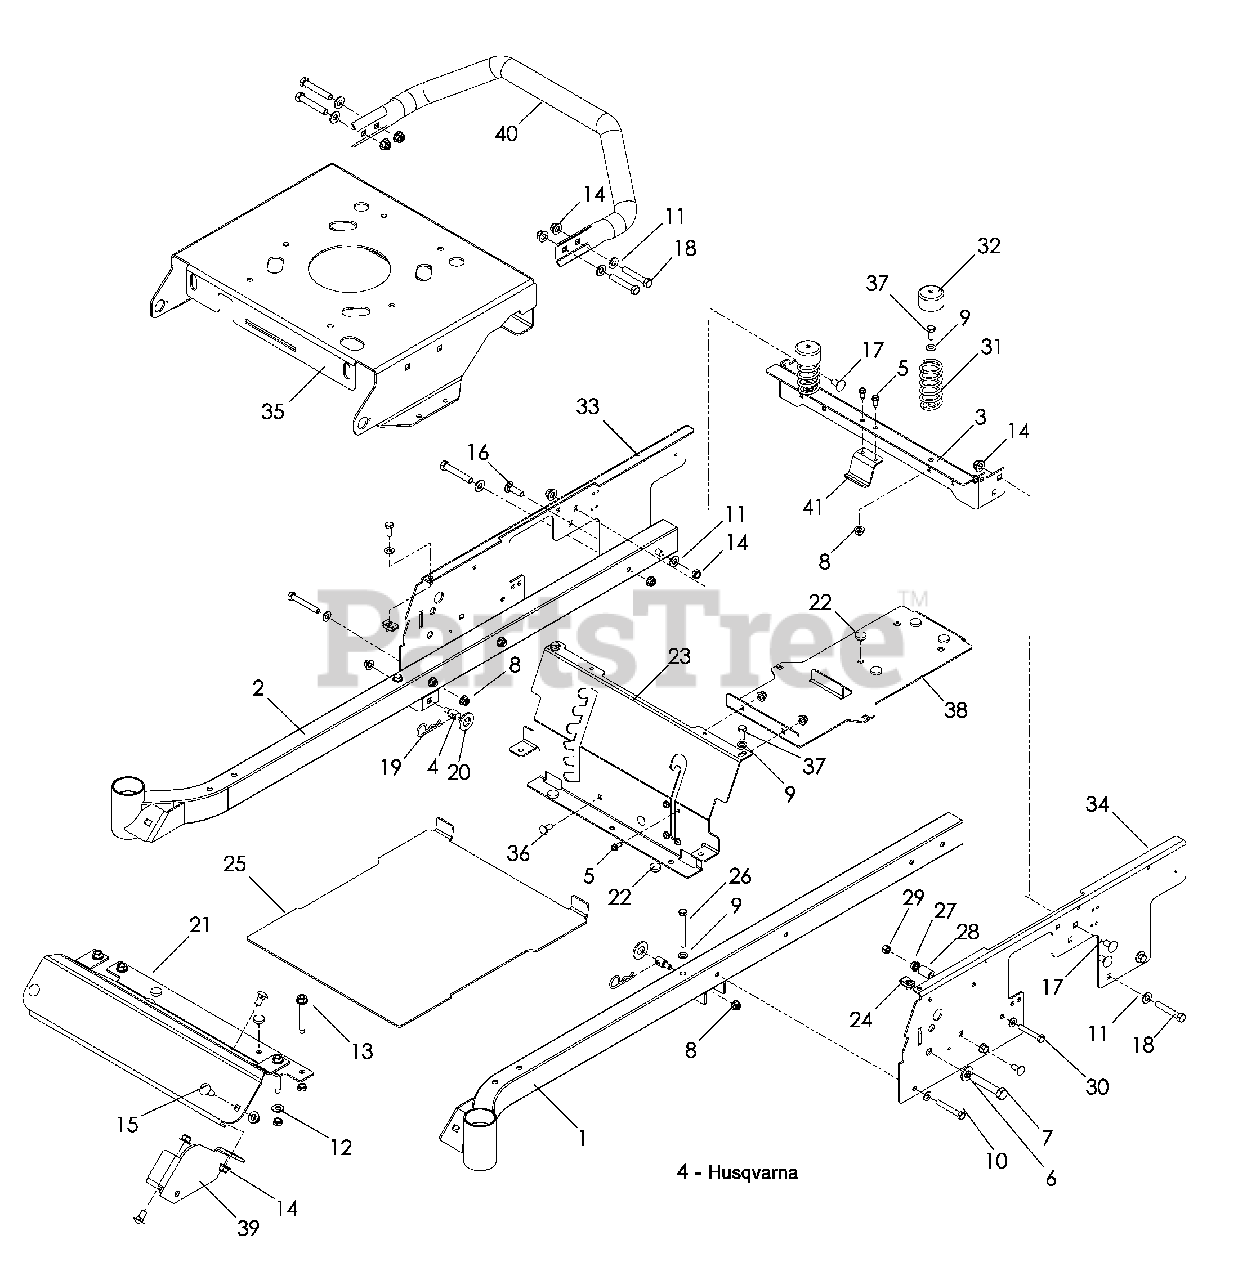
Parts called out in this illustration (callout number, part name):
1	FRAME TUBE, LH
2	FRAME TUBE, RH
3	SUPPORT, REAR SEAT
4	STUD w/ ANTI-ROTATE
5	SCREW ¼-20 x 5/8 SLF TAP
6	WASHER ½ SAE
7	HCS ½-13 x 2¾
8	NUT 5/16-18 FLANGE NYLOC
9	WASHER 5/16 SAE FLAT
10	HCS 5/16-18 x 2¼
11	WASHER 3/8 SAE FLT
12	NUT 3/8-16 HEX JAM NYLOC
13	BOLT 3/8-16 x 25/8 THD FRM
14	NUT 3/8-16 FLANGE NYLOC
15	RHSNB 3/8-16 x 1
16	RHSNB 3/8-16 x 1¼
17	RHSNB 3/8-16 x ¾
18	HCS 3/8-16 x 2¼
20	WASHER 5/8 SAE FLT
22	GROMMET,BUMPER
23	PANEL, SEAT SUPPORT
24	U TYPE RETAINER
25	FOOT PLATE
26	HCS 5/16-18 x 2¾
27	NUT 5/16-18 HEX WHIZLK
29	NUT 5/16-18 HEX NYLOC
30	HCS 5/16-18 x 2
31	SPRING, SEAT
32	CAP, SPRING
35	PLATE, ENGINE
36	RHSNB 5/16-18 x ¾
37	HCS 5/16-18 x ¾
38	SUPPORT, TANK
39	BRACKET, FRONT DECK
40	GUARD, REAR
41	BRACKET, FUEL TANK
